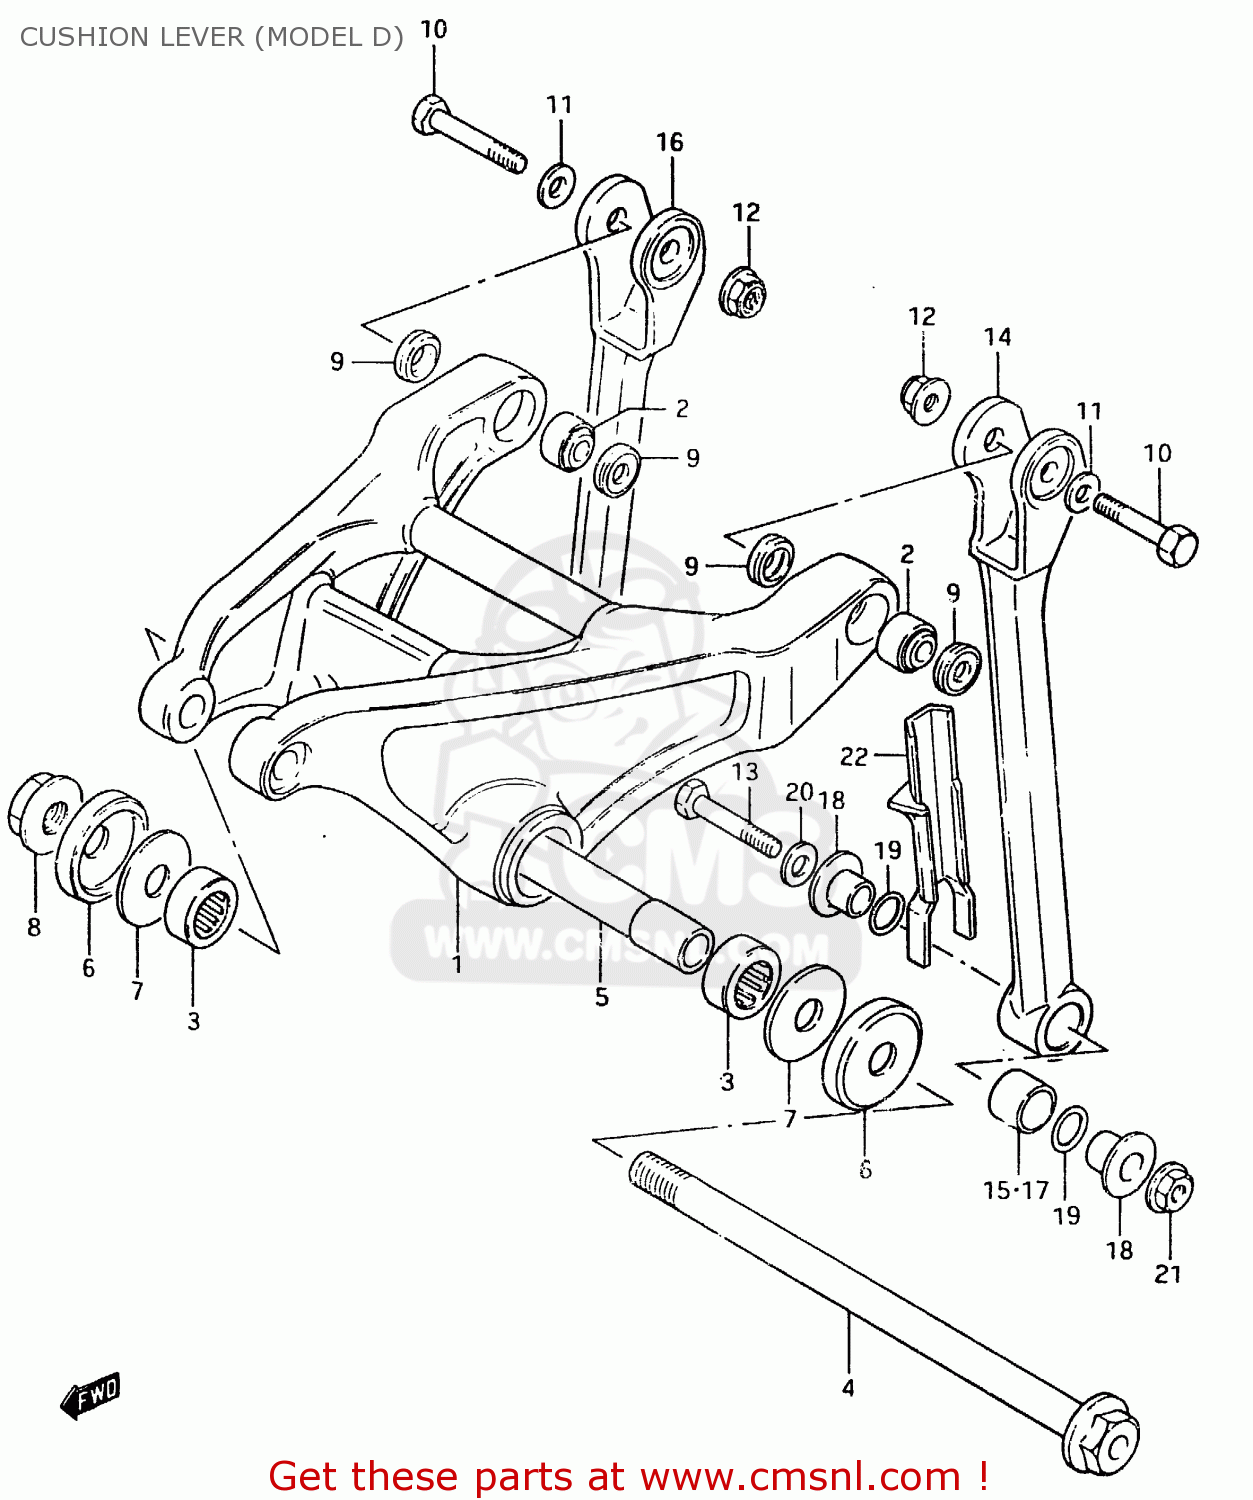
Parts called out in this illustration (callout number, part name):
1	LEVER SET,REAR CUSHION
2	BEARING(8X18X11)
3	BEARING(17X26X20)
4	SHAFT,REAR CUSHION LEVER
5	SPACER,REAR CUSHION LEVER
6	DUST SEAL
7	WASHER(12X35X2)
8	NUT 12MM
9	DUST SEAL,RR CUSHION LOD UPR
10	BOLT,REAR CUSHION LEVER
11	WASHER
12	NUT
13	BOLT,REAR CUSHION LEVER
14	LEVER SET,REAR CUSHION
15	BUSHING
16	LEVER SET,REAR CUSHION
17	BUSHING
18	SPACER,RR CUSHION ROD LWR
19	DUST SEAL,REAR CUSHION
20	WASHER
21	NUT
22	PROTECTOR,REAR CUSHION R
